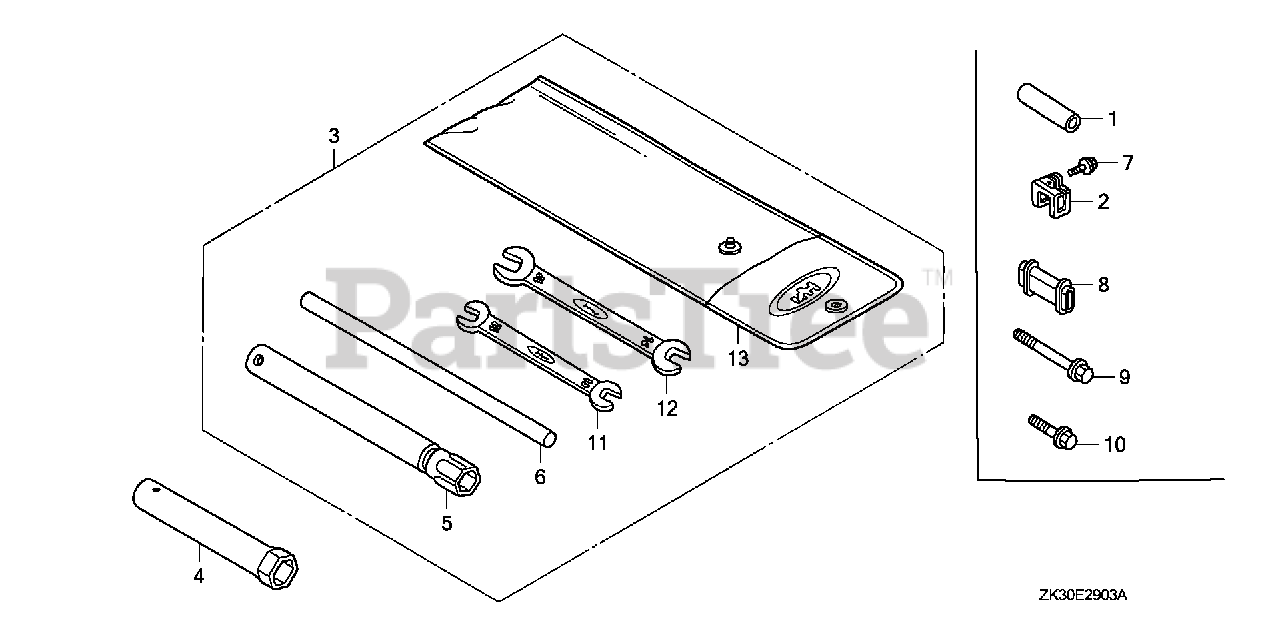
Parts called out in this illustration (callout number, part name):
3	TOOL KIT
5	WRENCH, SPARK PLUG
6	HANDLE, BOX WRENCH
11	SPANNER (10X12)
12	SPANNER (14X17)
13	BAG, TOOL (230MM)
